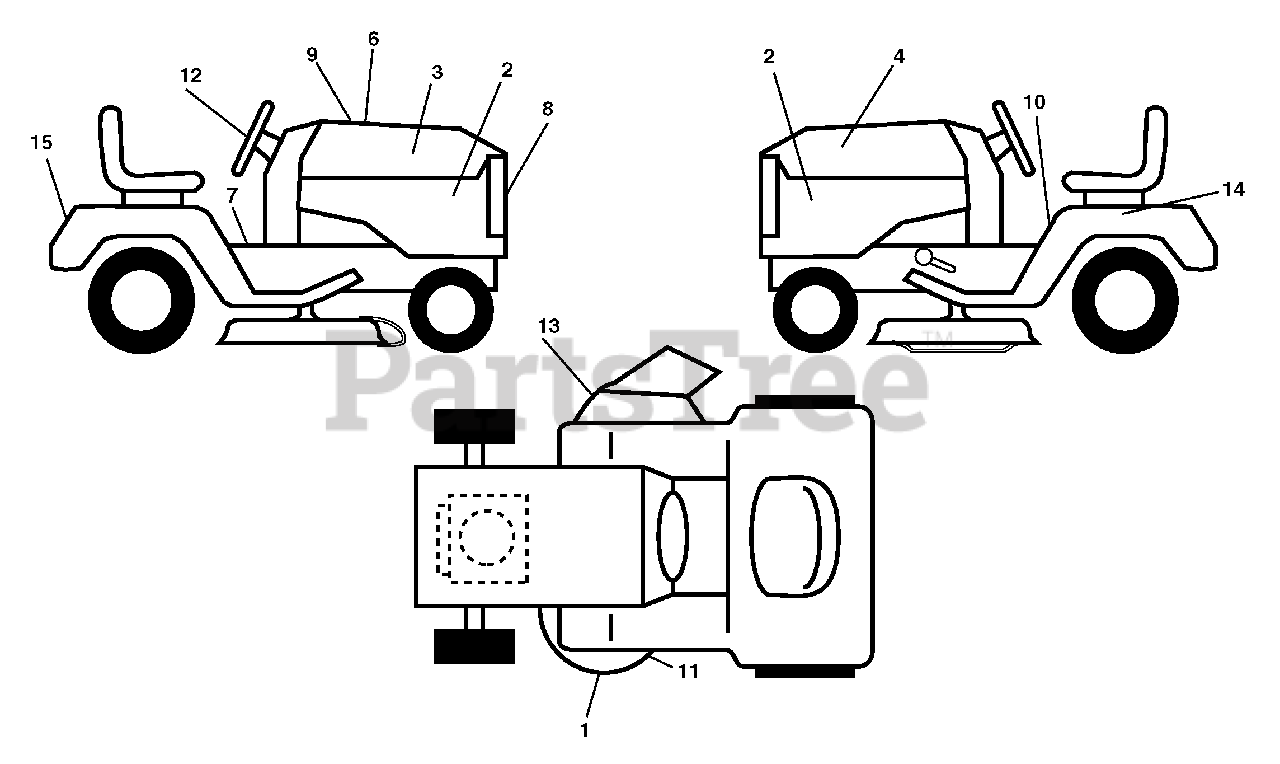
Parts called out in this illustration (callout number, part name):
1	Decal Deck Hvy Duty
2	Decal Panel Side
3	Decal Hood RH
4	Decal Hood LH
6	Decal Hood Cust. Resp.
7	Decal Operator
8	Decal Dash
9	Decal Replacement
10	Decal Fender Danger
11	Decal V-Belt Sch.
12	Decal Wheel Steering
13	Decal Warning
14	Decal Bat Dan/Psn
15	Decal Fender
